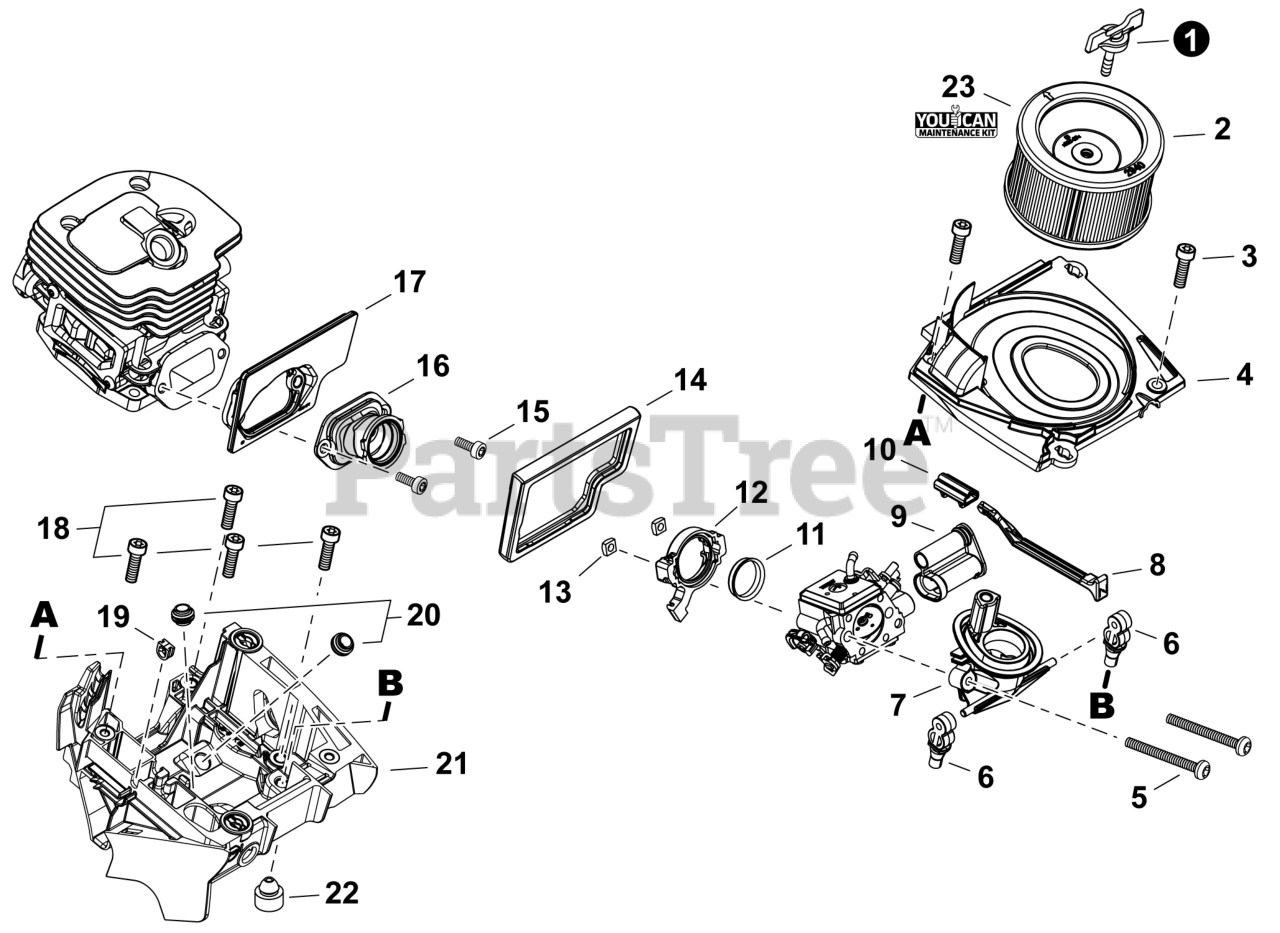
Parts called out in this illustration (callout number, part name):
1	THUMBSCREW
2	FILTER, AIR
3	BOLT, TORX 5x16
4	COVER, CARBURETOR CASE
5	BOLT 4x55
6	CUSHION
7	ELBOW, CARBURETOR
8	KNOB, CHOKE
9	GROMMET, NEEDLE
10	GROMMET, CHOKE
11	COLLAR 20
12	HOLDER, BELLOWS
14	CUSHION
15	BOLT, TORX 5x16
16	BELLOWS, INTAKE
17	INSULATOR, INTAKE
18	BOLT, TORX 5x20
19	GROMMET, LEAD
20	GROMMET, FUEL
21	CASE, CARBURETOR
22	CUSHION
23	TUNE-UP KIT - YOUCANT
